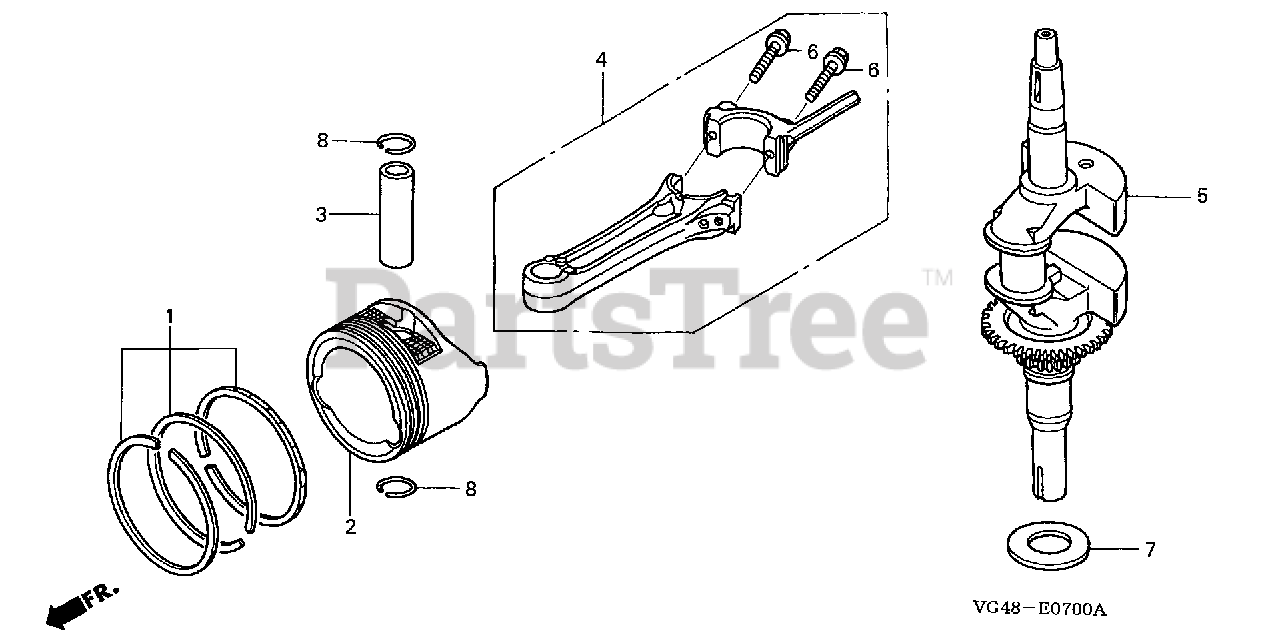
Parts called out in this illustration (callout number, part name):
1	RING SET, PISTON (RIKEN)
1	RING SET, PISTON (STD) (TEIKOKU)
2	PISTON
3	PIN, PISTON
4	ROD ASSY., CONNECTING
5	CRANKSHAFT
6	BOLT, CONNECTING ROD
7	WASHER, THRUST
8	CLIP, PISTON PIN (13MM)
